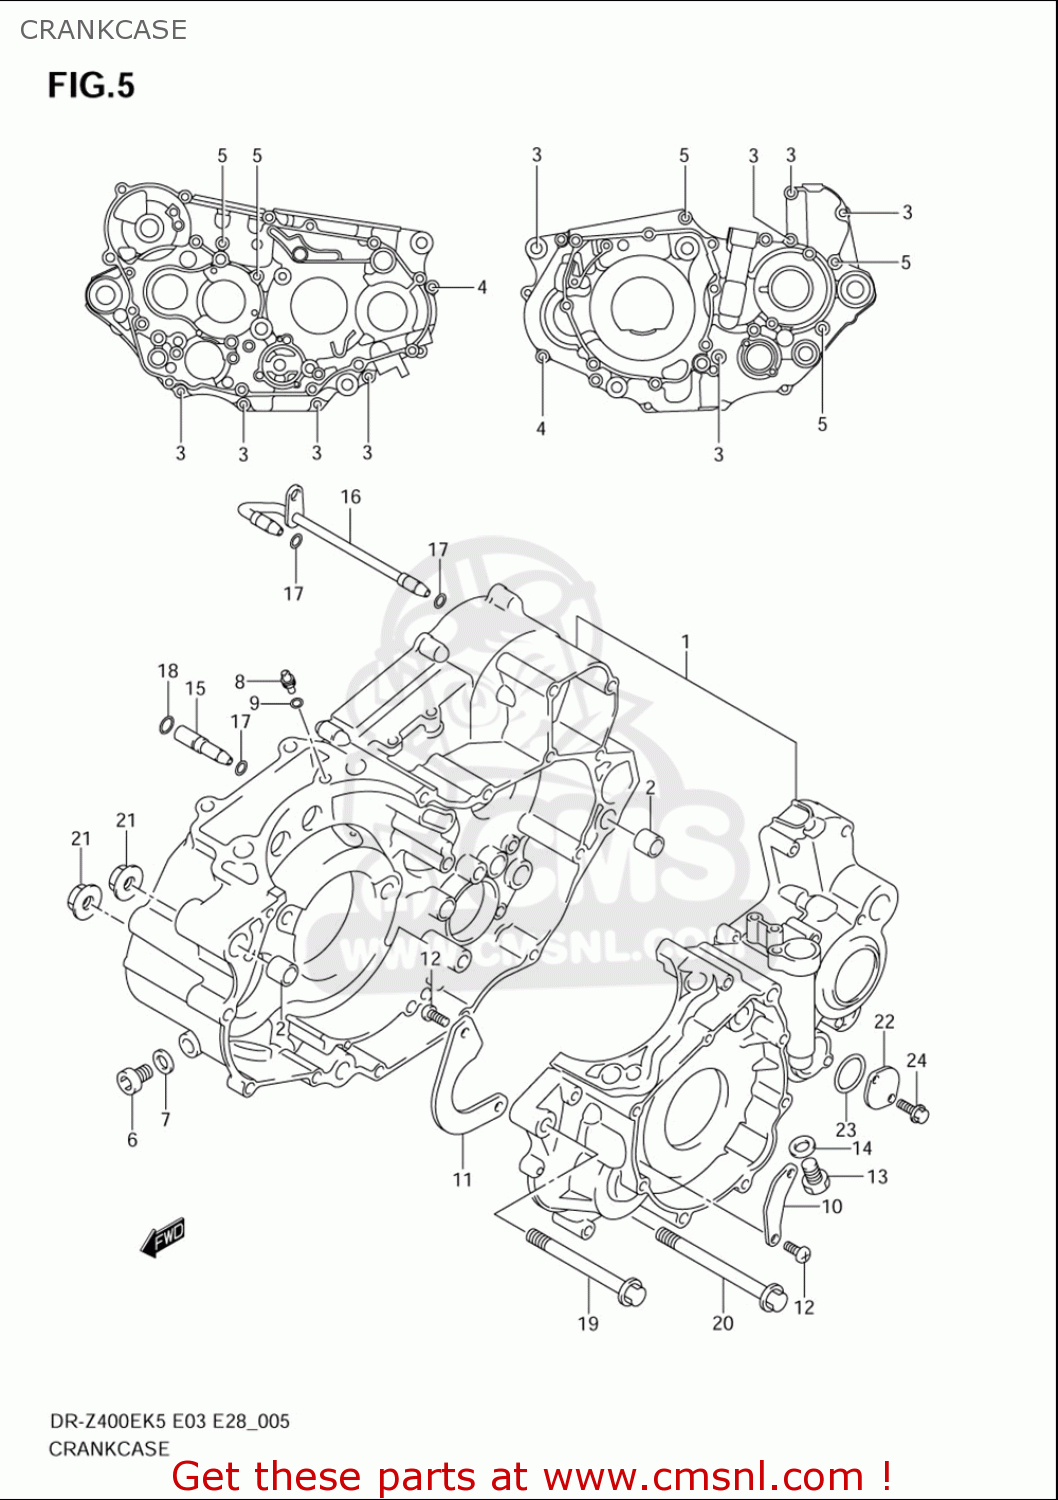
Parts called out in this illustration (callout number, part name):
1	CRANKCASE SET
2	PIN
3	BOLT
4	BOLT
5	BOLT
6	PLUG(10X10)
7	GASKET(10X14X3.6) (NAS)
8	JET(8)
9	O RING(D:1.2,ID:4)
10	SEPARATOR,CRANKCASE OIL NO.1
11	SEPARATOR,CRANKCASE OIL NO.2
12	BOLT(6X12)
13	PLUG(12X20)
14	GASKET(12.1X16.2X3.7) (NAS)
15	PIPE,OIL INNER NO.1
16	PIPE,T/M OIL INNER NO.2
17	O RING(D:1.9,ID:4.8)
18	O RING(D:1.9,ID:6.8)
19	BOLT(10X100)
20	BOLT(10X115)
21	NUT
22	CAP,GEAR SHIFT CAM PIVOT
23	O RING(D:2.4,ID:26.2)
24	BOLT
